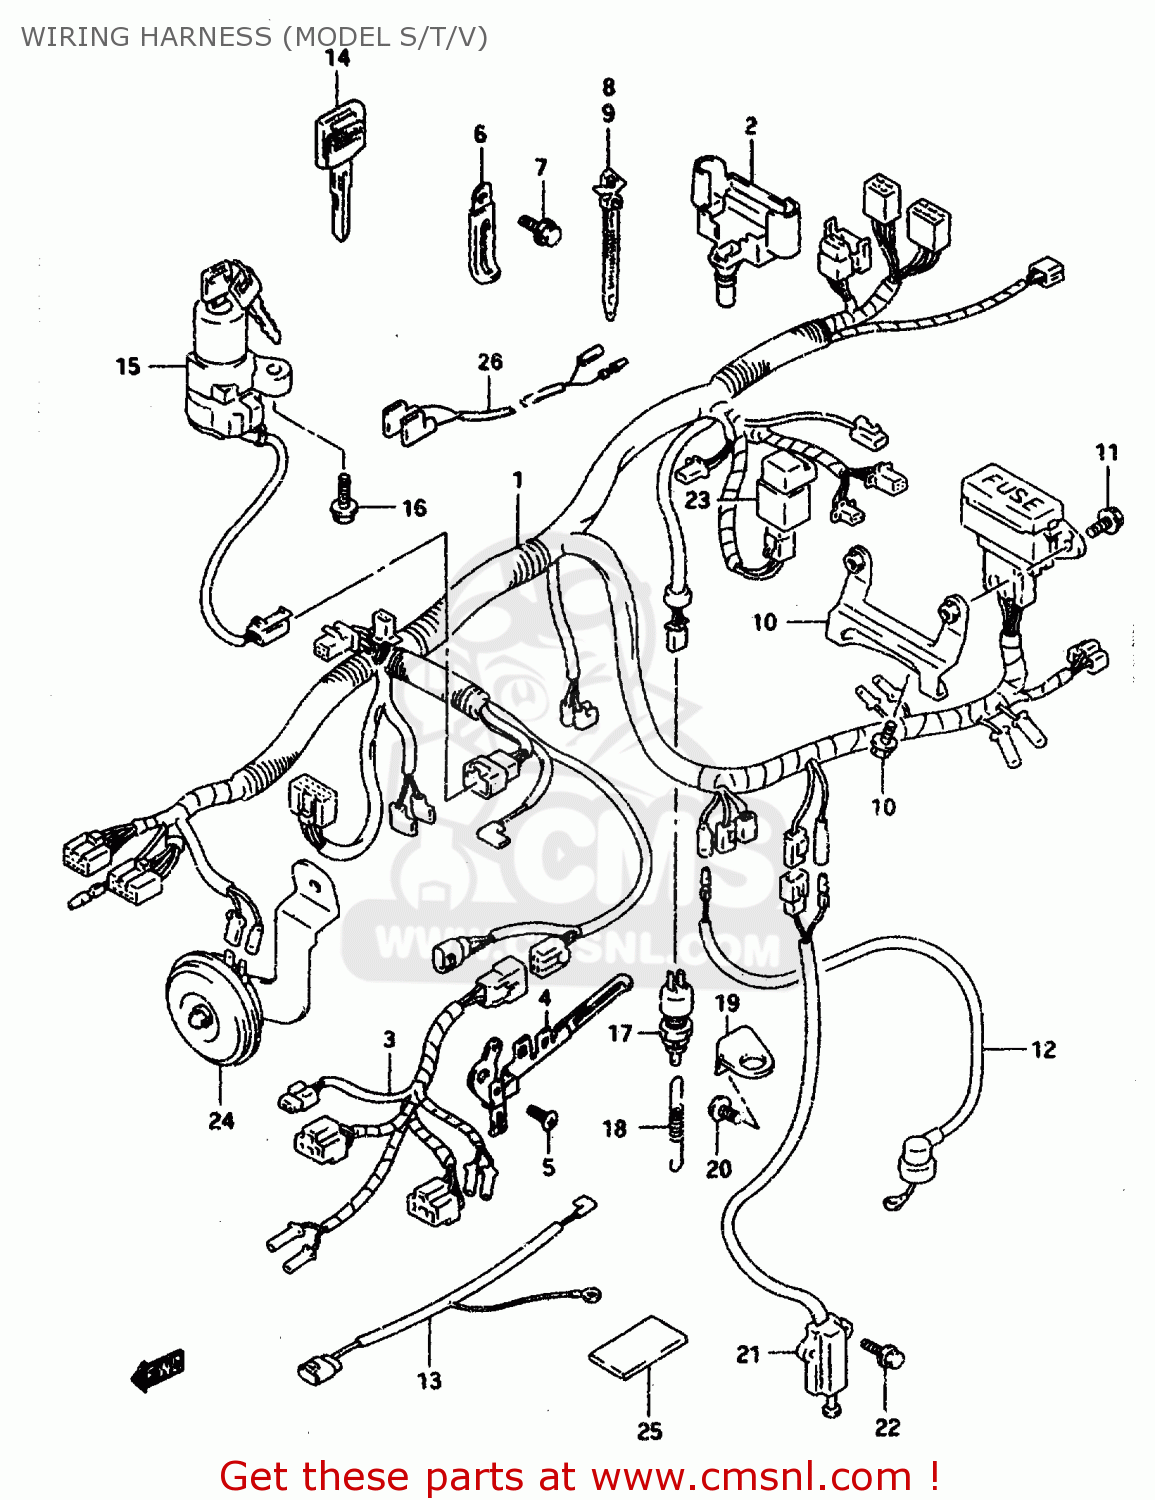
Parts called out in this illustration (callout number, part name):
1	HARNESS,WIRING
2	CAP,STARTER RELAY
3	HARNESS,WIRING NO.2
4	HOLDER COMP,COUPLER,LEFT
5	SCREW 5X8
6	CLAMP(L:65)
7	BOLT
8	CLAMP(L:95)
9	CLAMP(L:235)
10	BRACKET,FUSE BOX
11	BOLT
12	WIRE,OIL PRESSURE SWITCH LEAD
13	WIRE,WATER TEMPERATURE GAUGE
14	KEY,BLANK
15	LOCK ASSY,STEERING
16	BOLT M8X20
17	SWITCH ASSY,STOP LAMP
18	SPRING
19	BRACKET,STOP LAMP SWITCH
20	SCREW(6X12)
21	SWITCH ASSY,SIDE STAND WARNING
22	BOLT
23	RELAY ASSY
24	WIRE,HORN LEAD
25	TAPE
26	WIRE,CLUTCH LEAD
